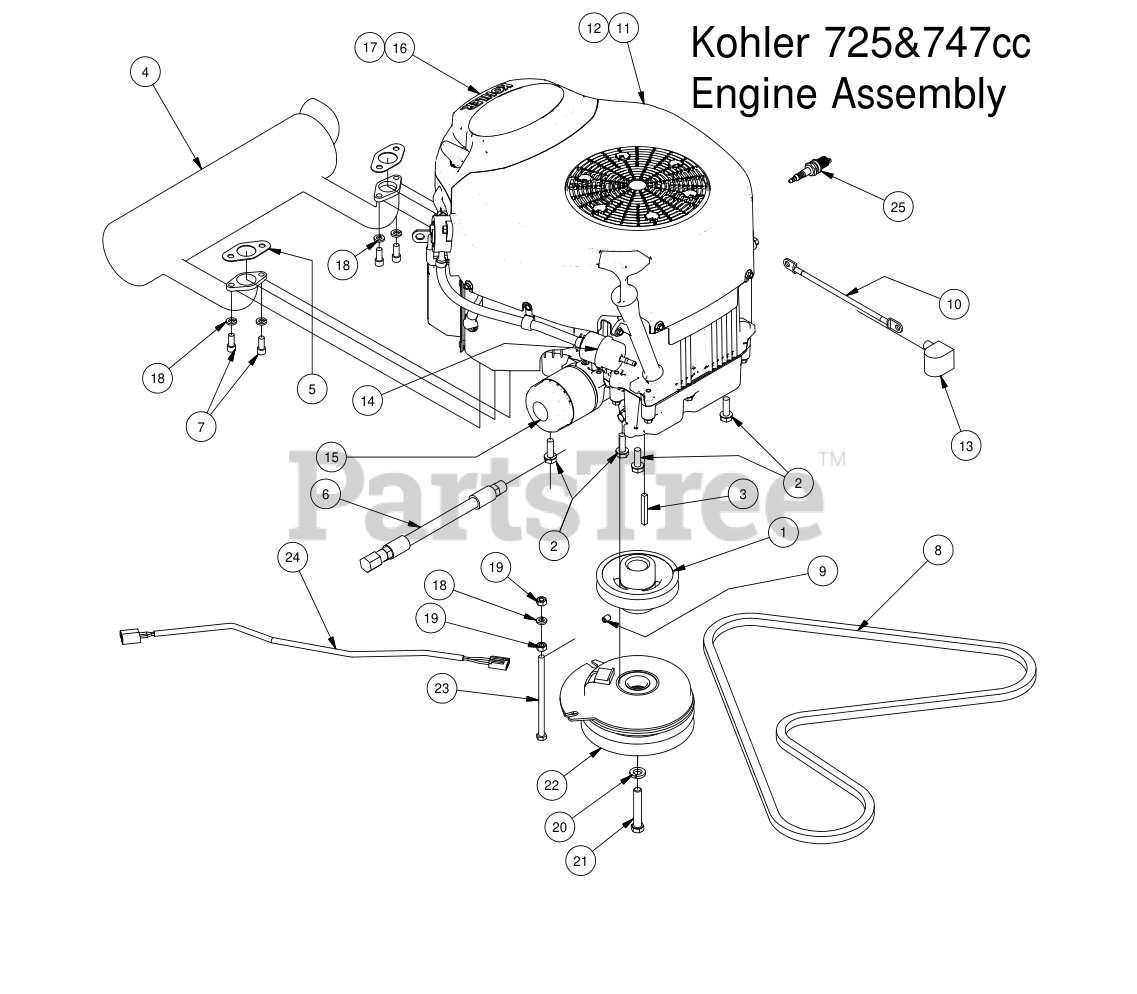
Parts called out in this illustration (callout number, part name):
1	4 3/4 Motor Pulley
2	3/8 x 1 1/8 bolt
3	1/4 x 2 Square key Stock
4	Kohler Exhaust
5	Exhaust Gasket
6	Oil drain Hose
7	5/16-18 x 3/4 Socket C/S
9	5/16 Set Screw
10	Ground Cable
11	Kohler-2014 ZT 725cc
12	Kohler-2014 ZT 747cc
13	Black Boot For Ground Cable
14	Universal Inline Fuel Filter
15	725 & 747 Kohler Oil Filter
16	725 & 747 Kohler precleaner ZT/MZ
17	725 & 747 Kohler Air Element ZT/MZ
18	5/16" Lock Washer
20	7/16" Lock Washer
21	7/16" x 2 1/2" Hex Bolt
22	Clutch Assembly
23	5/16-18 x 5-1/2 GR 5 Hex Bolt
24	Clutch Pigtail
25	Spark Plug
